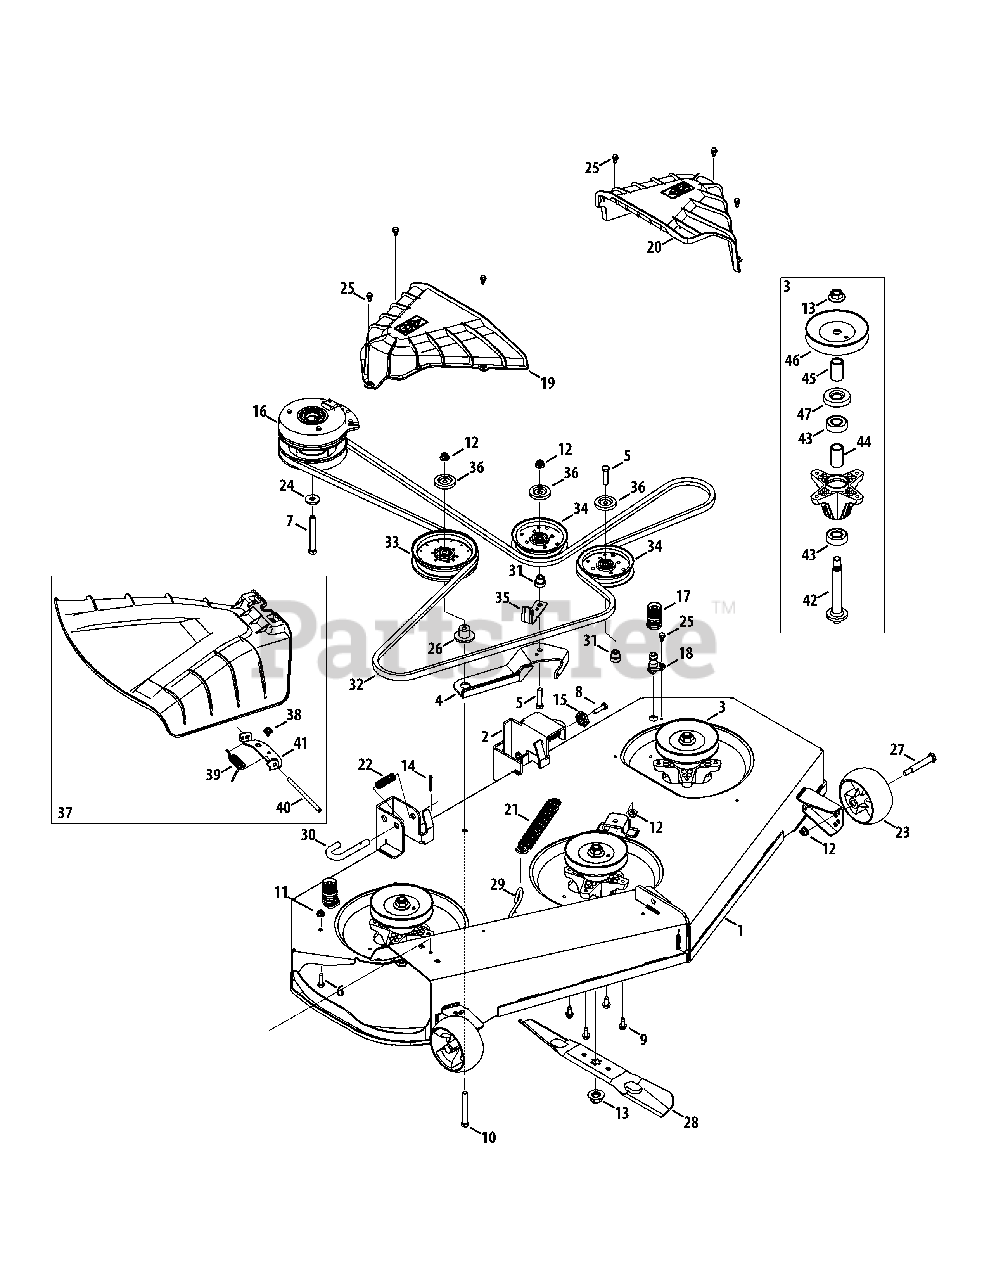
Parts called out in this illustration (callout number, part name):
1	54" Deck Fab
2	Deck Lift Bracket
3	Spindle Assembly
4	Idler Arm
5	Hex Cap Screw, 3/8-16 x 1.75
6	Hex Cap Screw, 5/16-18 x 1.00
7	Hex Cap Screw, 7/16-20 x 3.50
8	Hex Cap Screw, 5/16-18 x 1.25
9	Hex Washer Screw, 5/16-18 x .750
10	Hex Cap Screw, 3/8-16 x 3.25
11	Flange Lock Nut, 5/16-18
12	Flange Lock Nut, 3/8-16
13	Hex Flange Nut, 5/16-18
14	Cotter Pin, 5.32 x 1.25
15	Deck Adjustment Gear
16	Electric PTO Clutch
17	Water Nozzle Adapter
18	Deck Wash Nozzle
19	Belt Cover, RH
20	Belt Cover, LH
21	Extension Spring, 1.25 OD x 1.751
22	Compression Spring, .66 x 1.9
23	Deck Ball Wheel, 5.0
24	Flat Washer, .450 x 1.25 x .164
25	Shoulder Screw, .500 x 1/4-20
26	Shoulder Spacer
27	Shoulder Screw, .5 x 2.5 x 3/8-16
28	Blade, 18.67
29	Deck Spring Rod
30	Deck Hanger Rod
31	Shoulder Spacer
32	V-Belt
33	Idler Pulley, 5.00 Dia.
34	Idler Pulley, 4.25 Dia
35	Belt Guard Bracket
36	Pulley Cap
37	Chute Assembly
38	Screw, Sems, 1/4-20 x .50
39	Torsion Spring
40	Hinge Pin
41	Chute Bracket
42	Spindle Shaft, 6.11 Long
43	Ball Bearing
44	Spacer, .792 x 1.060 x 1.860
45	Spacer, .792 x 1.060 x 1.782
46	Deck Pulley
47	Bearing Shield
